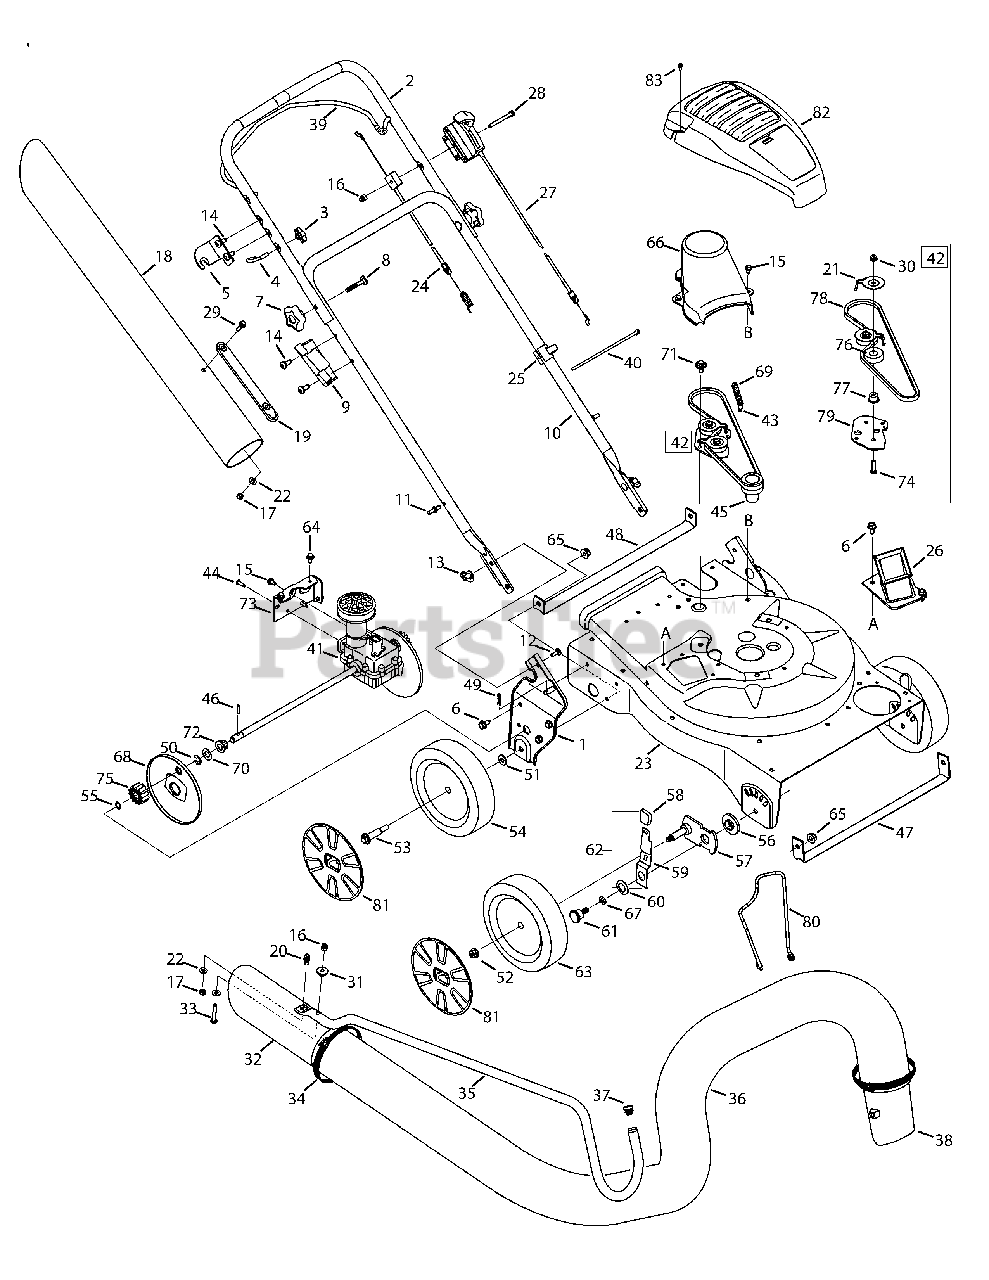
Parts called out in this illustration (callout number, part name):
1	Handle Bracket Ass’y RH
2	Upper Handle
5	Upper Handle Bracket
6	Hex Cap Screw, 5/16-12 x.750
7	Handle Knob, 5/16-18
8	Carriage Bolt
9	Nozzle Handle Clip
12	Carriage Screw, 1/4-20 x.75
13	Wing Nut, 1/4-20
14	TT Screw, 5/16-18 x .750
15	Screw, 1/4-20 x .500
16	Cap Lock Nut, 1/4-20
17	Hex Lock Nut, 1/4-20
18	Hose Extension
19	Chute Strap
21	Belt Keeper
22	Flat Washer.271 ID x.630 OD
23	Upper Flail Housing
24	Drive Control Cable
25	Cable Guide
26	Chipper Chute Assembly
27	Speed Control Cable
28	Hex Screw, 1/4-20 x 2.50
29	Screw, 1/4-20 x .75
30	Flange Lock Nut, 1/4-20
32	Hose Nozzle
33	Hex Cap Screw, 1/4-20 x 2.625
34	Adjustment Clamp
36	Vacuum Hose
37	Handle Plug
38	Hose Adapter
39	Drive Control
40	Cable Tie
41	Transmission Assembly
42	Idler Assembly (Incl. Ref.# 76-79)
43	Shoulder Screw, #12-24 x .30 x .46
44	Screw, #12-16 x .750
45	Impeller Hub
46	Dowel Pin
47	Front Wheel Support Brace
48	Rear Wheel Support Brace
49	Cotter Pin
51	Flat Washer, .406 x .875 x .105
52	Flange Lock Nut, 3/8-16
53	Shoulder Screw, 3/8-16
54	Wheel, 8 x 2
55	Snap Ring
56	Height Adjustment Bearing
57	Pivot Arm Assembly
58	Height Adjustment Knob
59	Spring Lever
60	Bell Washer, .760 ID x.25 OD
61	Shoulder Screw, .750 x.500
62	Height Lever Assembly (Incl. Ref.# 58-59)
63	Wheel 8 x 2
64	Screw, 1/4-20 x .625
65	Flange Lock Nut, 3/8-16
66	Belt Cover
67	Thrust Washer, .375 ID x.70 OD
68	Wheel Cover
69	Extension Spring, .375 x 2.95
70	Flat Wash, .508ID x1.00OD x.020
71	Shoulder Screw, .560 x.165
72	Drive Axle Bushing
73	Transmission Mounting Bracket
74	Screw, 1/4-20 x 1.00
75	Spur Gear - RH
76	Ball Bearing
77	Flange Spacer,.260 x.659 x.517
78	Belt, 3/8 x 32.5
79	Idler Bracket
80	Tube Holder
81	Hubcap, 8"
82	Engine Shroud
83	Screw, #10-16 x 1.25
